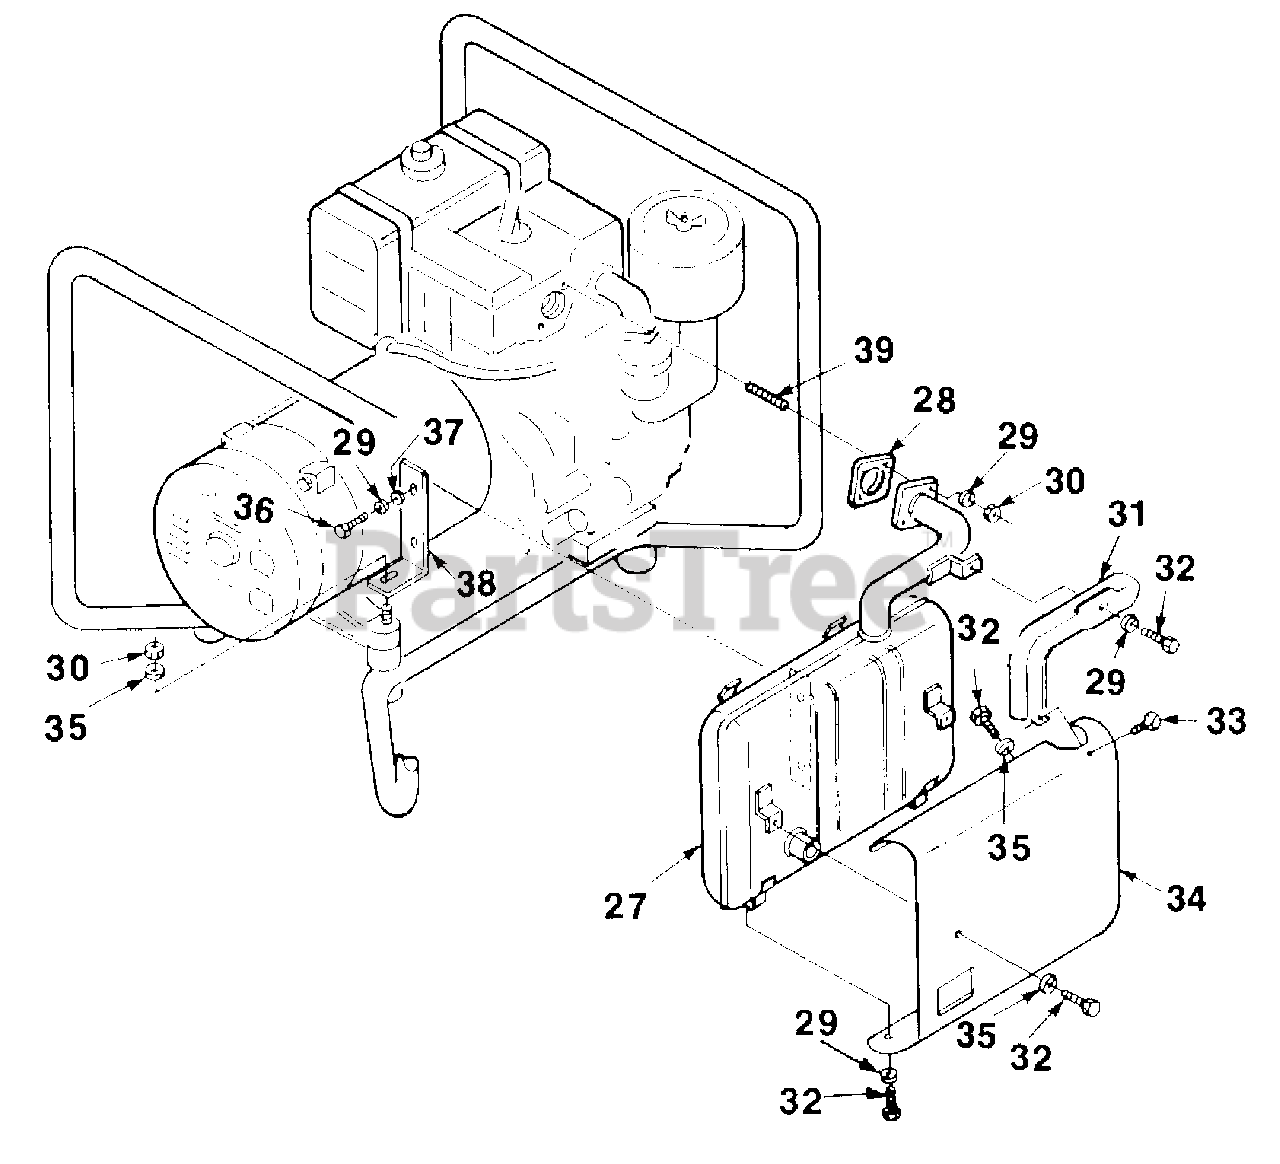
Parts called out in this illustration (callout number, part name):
27	MUFFLER
28	GASKET- Muffler
29	WASHER- Lock (1/4")
30	NUT- (1/4-28)
31	SHIELD- Exhaust
32	BOLT- (1/4-20 x 1/")
33	SCREW- (8-18 x 3/8")
34	SHIELD- Muffler
35	WASHER- Lock
36	BOLT- (1/4-20 x 1/2")
37	WASHER- Flat
38	BRACKET- Support
39	STUD
